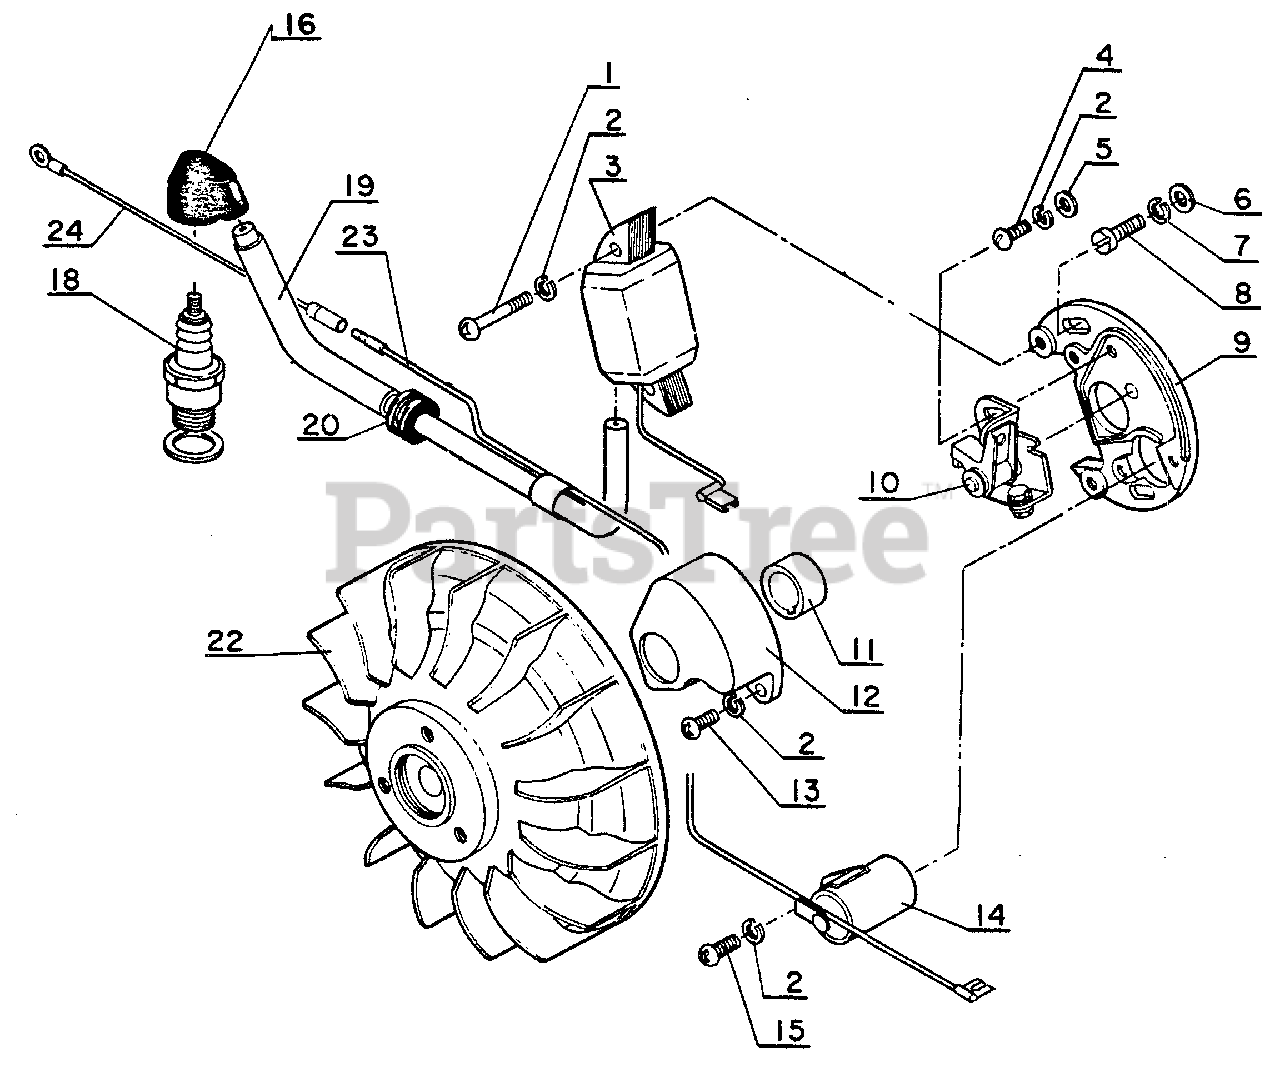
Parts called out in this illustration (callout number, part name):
1	SCREW - 4X22
2	LOCKWASHER - 4
3	COIL, IGNITION
4	SCREW - 4X8
5	WASHER - 4
6	WASHER - 5
7	LOCKWASHER - 5
8	SCREW - 5X15
9	CONTACT POINT SET
10	ARM, BREAKER
11	CAM
12	Brecher cover
13	SCREW - 4X12
14	CONDENSER
15	SCREW - 4X8
16	CAP, SPARK PLUG
18	SPARK PLUG -- BM-6A
19	TUBE
20	BUSHING
22	FLYWHEEL
23	LEAD - GROUND
24	LEAD - GROUND
